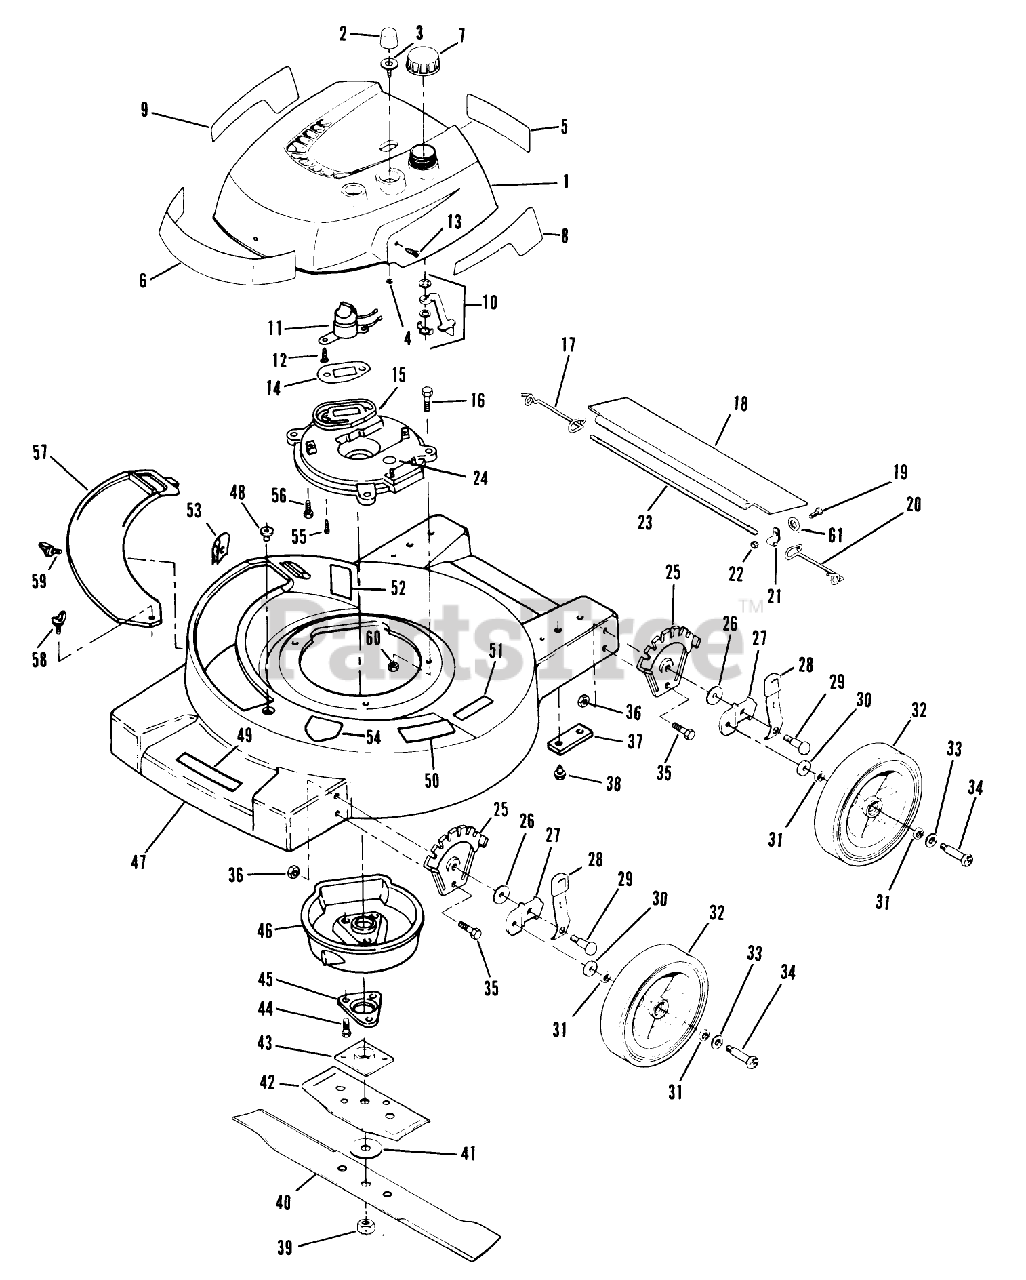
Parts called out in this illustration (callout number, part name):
4	LOCKNUT S
13	SCREW S
15	PLATE,MUFFLER F
16	SCREW
17	SPRING;TRAILING SHIELD RH
18	SHIELD
20	SPRIG T/SHLD ASOC
21	CLAMP ROD KMC
22	LOCKNUT E
23	ROD 21" ADVANCE
26	WASHER
30	WASHER WROUGHT
31	WASHER
33	SPACER
34	BOLT WHEEL
36	LOCKNUT
38	SCREW
39	NUT-BLADE
41	WASHER
43	PLATE AND COLLAR ASM
44	SCREW
45	SUPPORT F
50	PAD FOOT
55	SCREW V
57	PLATE
58	WING SCREW LAWRE
60	NUT-LOCK F
61	WASHER F
